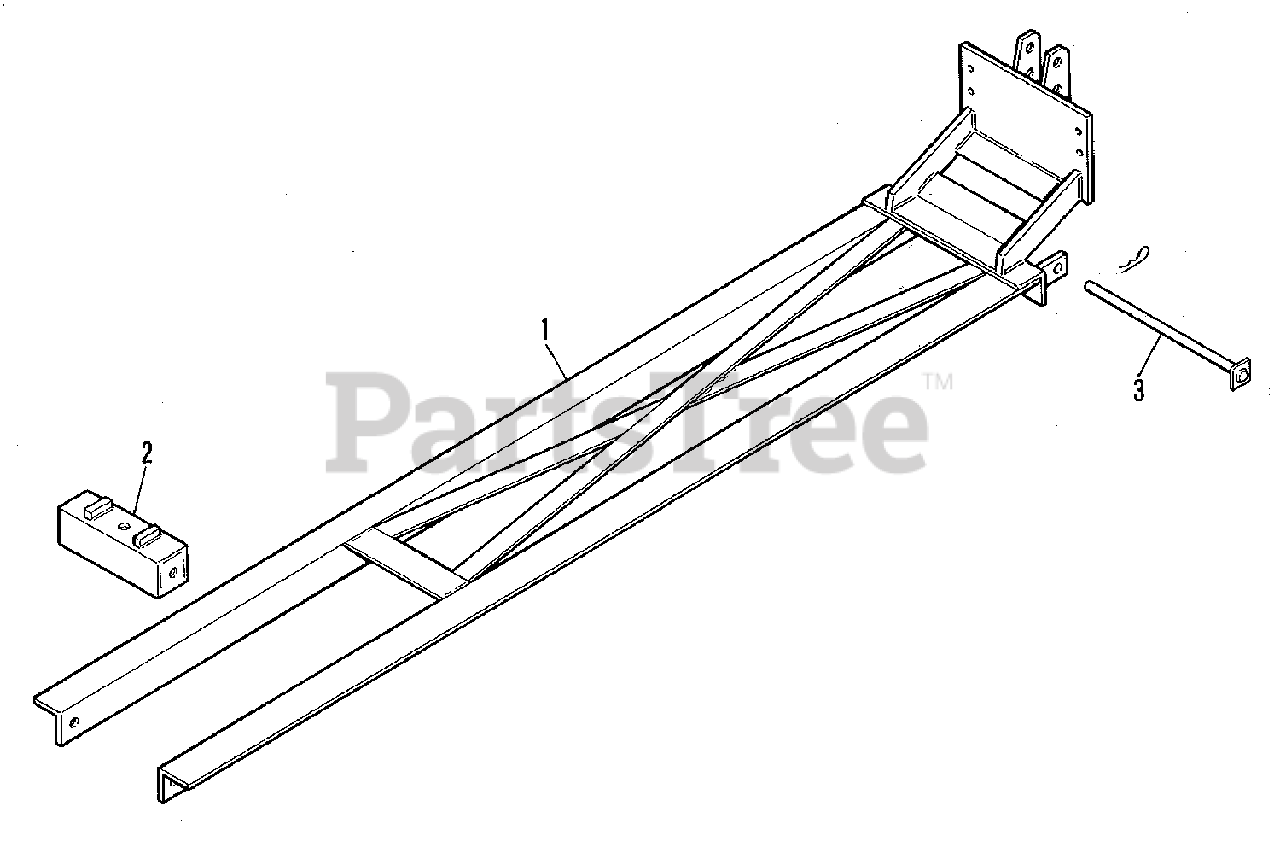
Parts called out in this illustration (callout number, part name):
1	RAIL ASSEMBLY, Undercarriage
1	CAPSCREW, 1/2NC x 2
1	LOCKWASHER, 1/2
2	RAIL ASSEMBLY, Rear Mount
2	CAPSCREW, 3/4NC x 4
2	CAPSCREW, 3/4NC x 2-1/2
2	LOCKWASHER, 3/4
3	PIN ASSEMBLY, A-Frame
3	CLIP, Hairpin
